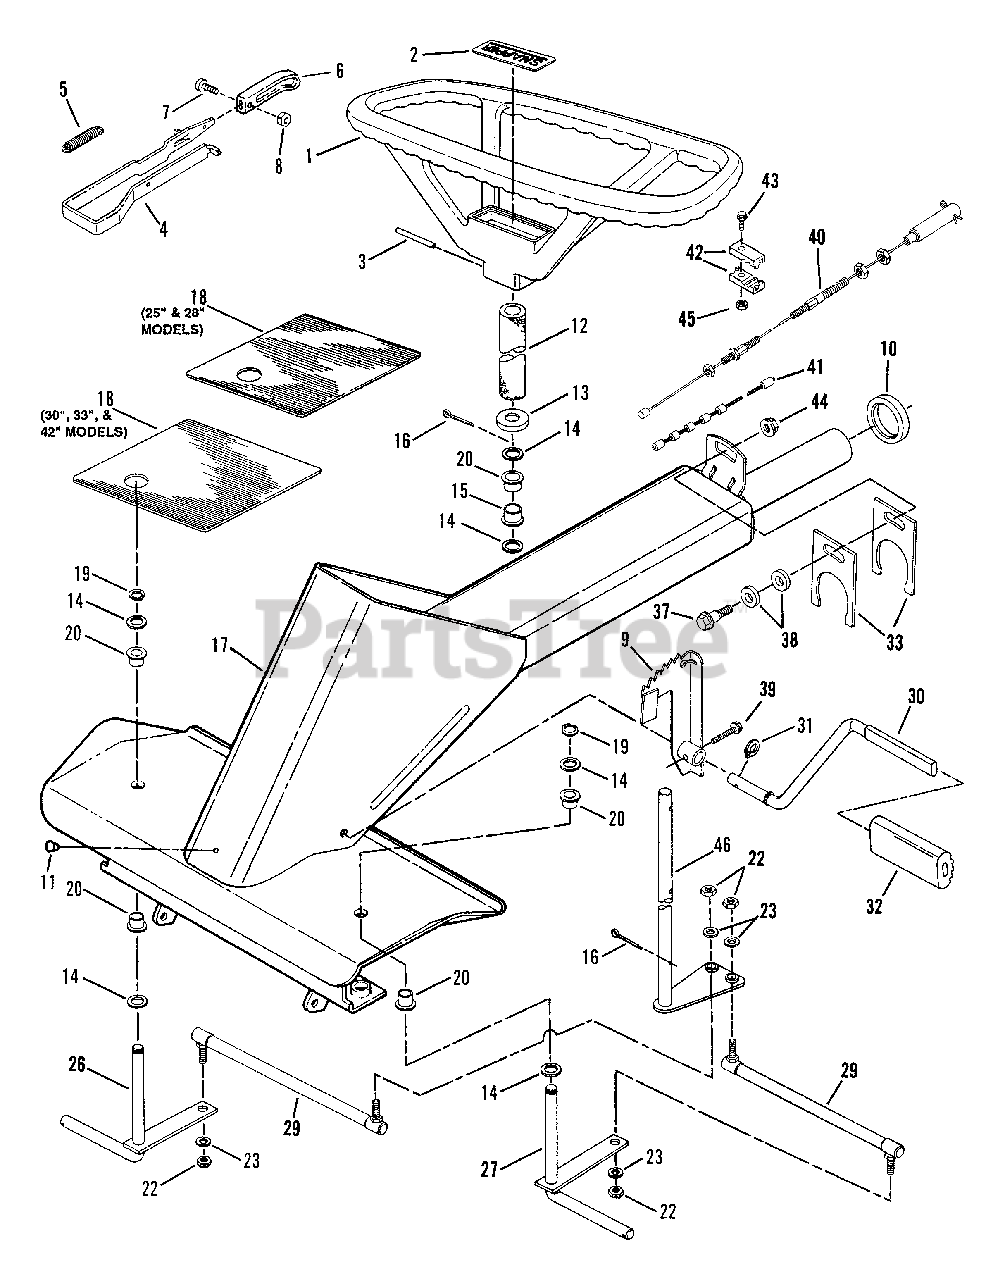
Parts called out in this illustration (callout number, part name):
1	ASSEMBLY, Steering Wheel
2	DECAL, Snapper
3	PIN, 1/4 x 1-1/2" Roll
4	BRACKET, Clutch/Brake
5	SPRING
6	KNOB
7	SCREW, #8-32 x 3/8" Cross Recess
8	NUT, #8-32 Hex
9	ARM, Clutch/Brake
10	SPACER, Main Tube
11	PLUG
12	COVER, Steering Shaft (Foam)
13	COVER
14	WASHER, 314 Flat
15	BUSHING, 3/4" Steering Shaft
16	PIN, 3/16 x 1-1/2" Cotter
17	FRAME, Front
18	PAD, Foot
19	RING, Retaining
20	BEARING
22	NUT, 5/16-24 Hex
23	WASHER, 5/16 Split Lock
26	PIN, Wide King (Right Side)
27	PIN, Wide King (Left Side)
29	TIE-ROD
30	PEDAL, Clutch/Brake
31	RING, 5/8" External Retaining
32	PAD, Clutch/Brake Pedal
33	SPACER, Pivot
37	BOLT, 318-24 x 5/8" Hex Shoulder
38	SPACER
39	SCREW, 5/16-1 8 x 1-1/4" Self-Tapping
40	CABLE, Brake
41	CABLE, Clutch
42	UNION, Cable
43	BOLT, 1/4-20 x 3/4" Hex Flange Lock
44	NUT, 3/8-24 Hex Flange Lock
45	NUT, 1/4-20 Hex Center Lock
46	SHAFT, Steering (Wide Front End)
